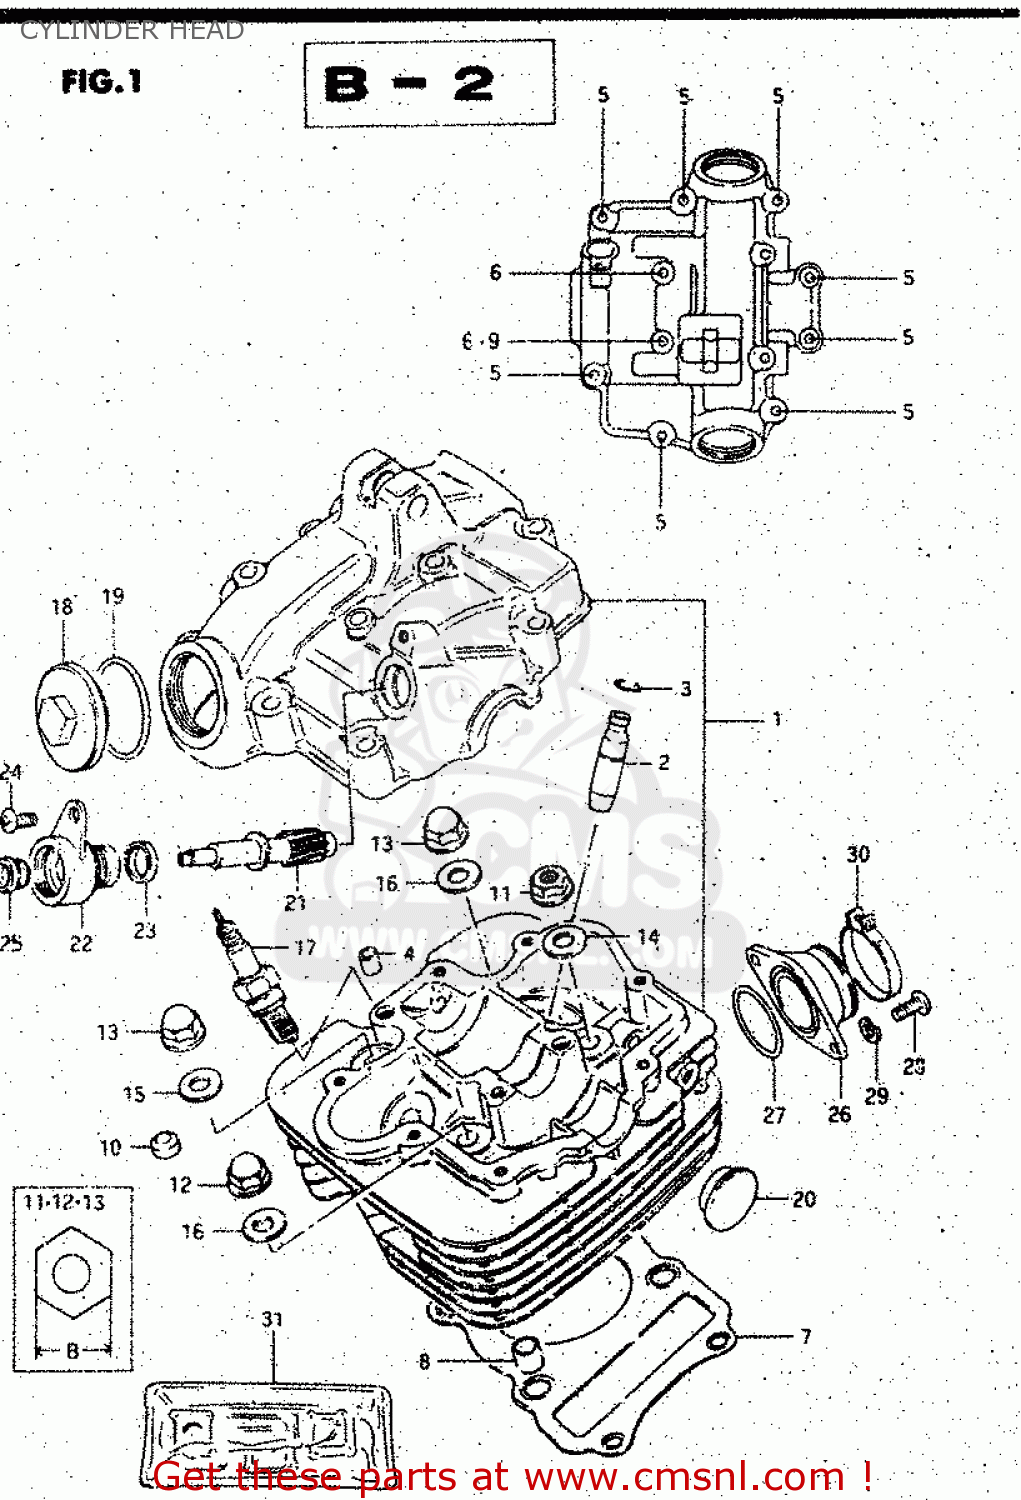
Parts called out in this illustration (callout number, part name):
1	HEAD ASSY,CYLINDER
2	GUIDE,VALVE
3	RING,SNAP
4	PIN(6.2X8X11)
5	BOLT 6X35
6	BOLT
7	GASKET,CYLINDER HEAD (NAS)
8	PIN
9	GASKET(5.8X13X1.2) (NAS)
10	PAD,CYLINDER HEAD
11	NUT
12	NUT
13	NUT (8MM)
14	WASHER(8.5X19X2.3)
15	WASHER (8.5X19X2.3)
16	GASKET (NAS)
17	SPARK PLUG D8EA
18	CAP,INSPECTION
19	O RING(D:3,ID:29.5)
20	PLUG(OD:22.5)
21	GEAR,TACHOMETER DRIVEN
22	SLEEVE,TACHOMETER DRIVE GEAR
23	SEAL,TACHOMETER DRIVEN
24	SCREW(5X12)
25	SEAL,OIL(5X12X8)
26	PIPE,INTAKE
27	O RING(D:2.4,ID:31.7)
28	SCREW
29	WASHER,LOCK
30	CLAMP
31	GASKET SET
